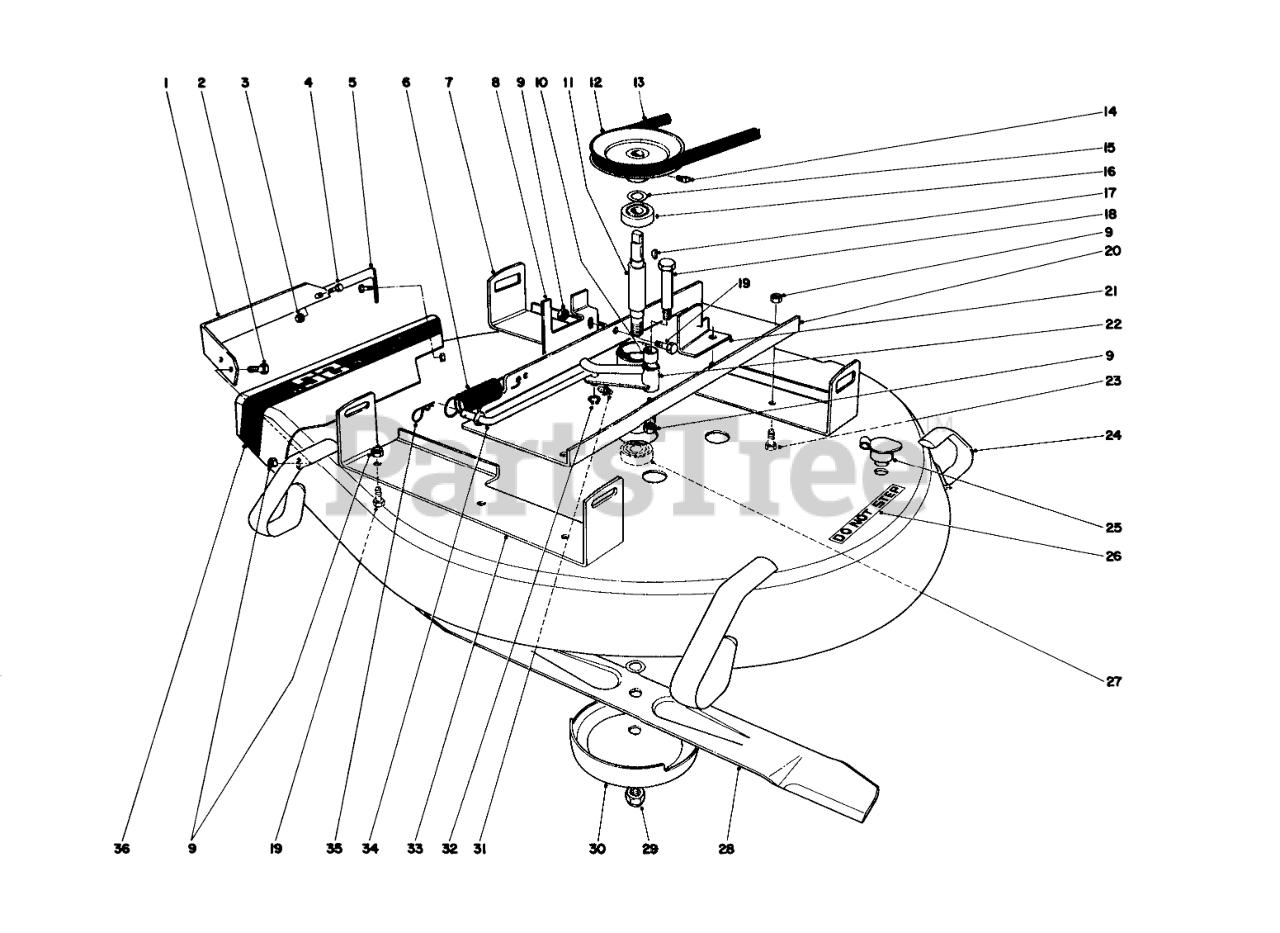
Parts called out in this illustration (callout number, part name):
1	Deflector Bar
2	SCREW-HH
3	NUT-LOCK, SIDE
4	SCREW-HWH
5	Brace Deflector Bar
6	Spring
7	Hanger-Rear Deck
8	Belt Retainer
9	NUT-LOCK, CONE
10	BUSHING
11	BLADE SPINDLE
12	Pulley
13	DECK DRIVE V-BELT
14	SCREW-SQH
15	WASHER
16	Bearing
17	KEY-WOODRUFF
18	BOLT-SHOULDER, HH
19	SCREW-HH
20	Bearing Housing
21	Belt Retainer
22	Bracket Arm (Incl. Ref. #10)
23	Screw
24	Mower Housing
25	WASHOUT PLUG
26	Decal
27	.6693 RP BALL BEARING
28	Blade
29	NUT-LOCK, CONE
30	Cup
31	FITTING-GREASE
32	RING-GRIP
33	Hanger-Front Deck
35	PIN-COTTER, HAIR
36	Chute Deflector Decal
